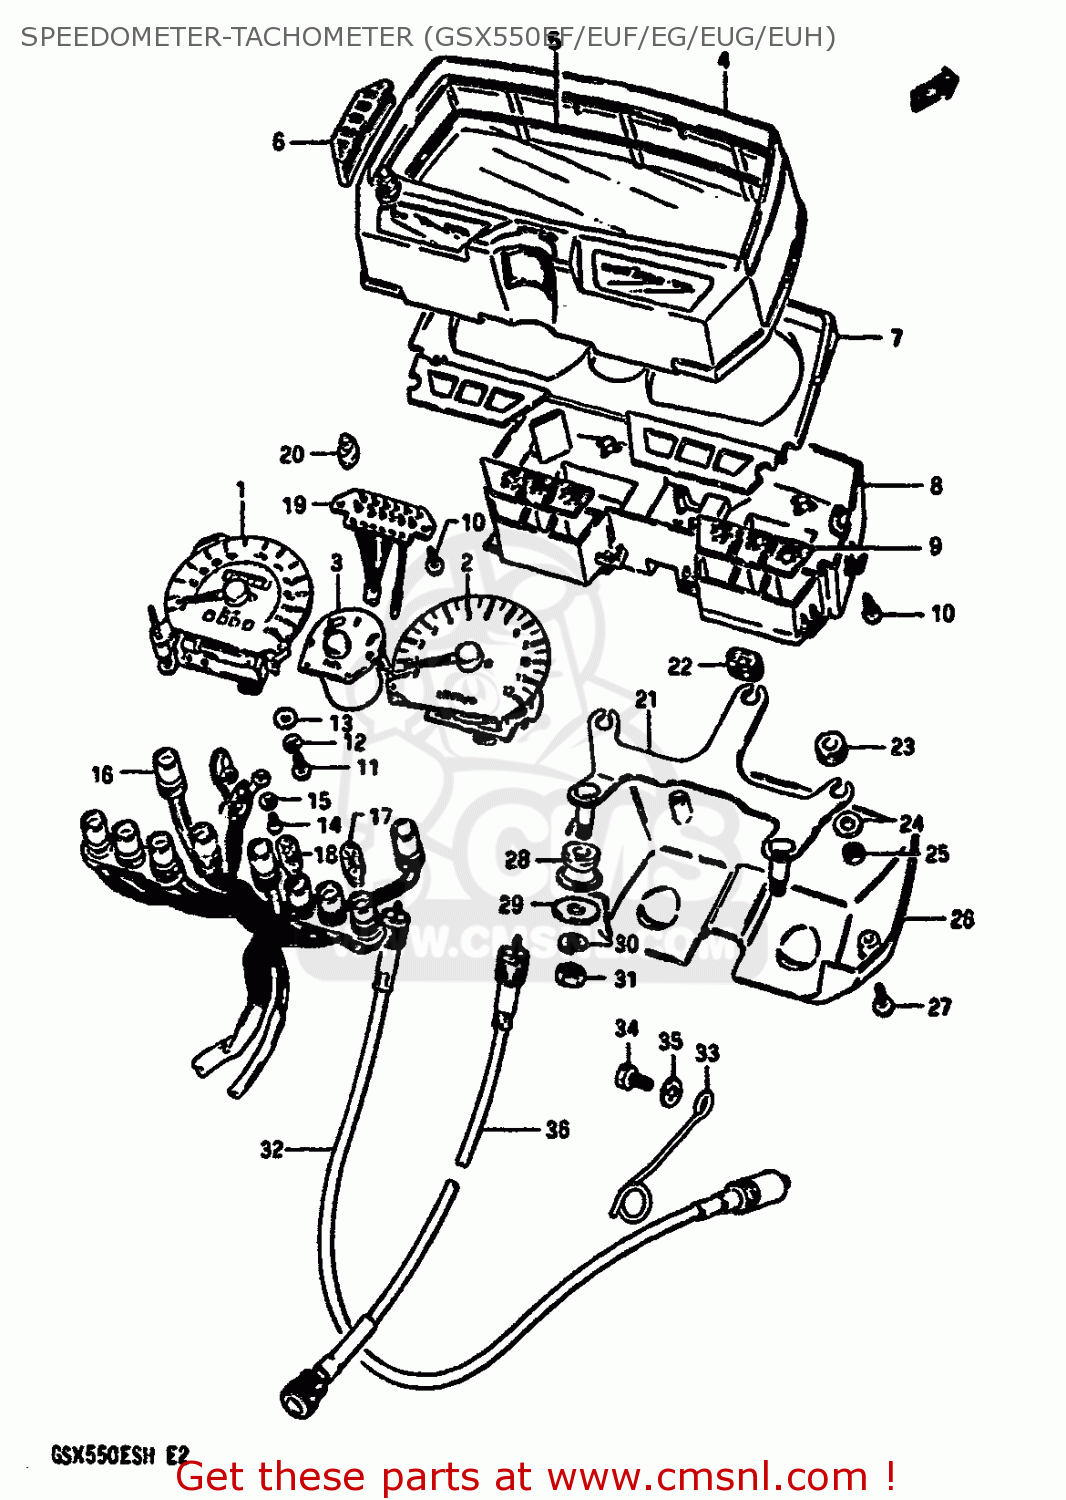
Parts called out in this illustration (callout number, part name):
1	SPEEDOMETER (KILO)
2	METER,TACHOMETER
3	METER,FUEL
4	HOOD,METER
5	GLASS,SPEEDOMETER
6	CUSHION,METER CASE
7	PLATE, WINDOW
8	CASE,METER,INNER
9	LENS SET,PILOT
10	SCREW,GEAR INDICATOR
11	SCREW
12	LOCK WASHER
13	WASHER
14	SCREW
15	WASHER
16	SOCKET
17	BULB(12V3.4W,T10,BF175-01450A)
18	BULB(12V1.7W,T10,WB121)
19	SOCKET,GEAR INDICATOR
20	BULB(14V1.12W)
21	BRACKET,METER
22	CUSHION,METER
23	CUSHION,METER
24	WASHER
25	NUT
26	COVER,METER,UNDER
27	SCREW
28	CUSHION,METER BRACKET
29	WASHER (8.5X20X1.6)
30	WASHER,LOCK,8.
31	NUT
32	CABLE ASSEMBLY,SPEEDOMETER
33	CLAMP,SPEEDOMETER CABLE
34	BOLT
35	WASHER
36	CABLE ASSY,TACHOMETER
